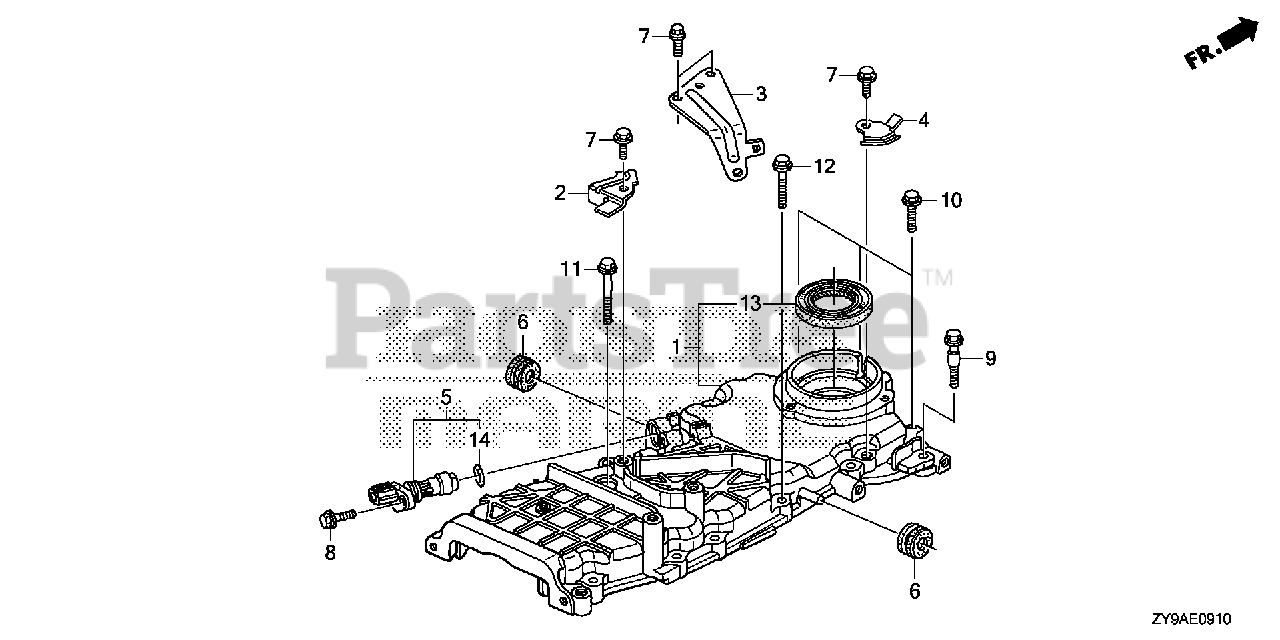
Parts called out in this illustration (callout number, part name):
1	CASE, CHAIN *NH8* (DARK GRAY)
2	BRACKET A, HARNESS CLIP
3	BRACKET C, HARNESS CLIP
4	BRACKET E, HARNESS CLIP
5	SENSOR ASSY., CRANK
6	GROMMET, CASE (LOWER)
7	BOLT, FLANGE (6X14) (CT200)
8	BOLT, FLANGE (6X16)
9	BOLT, SPECIAL (6X31)
10	BOLT, FLANGE (6X22)
11	BOLT, FLANGE (6X40)
12	BOLT, FLANGE (6X28)
13	OIL SEAL (40X55X7) (NOK)
14	O-RING (15X1.9)
